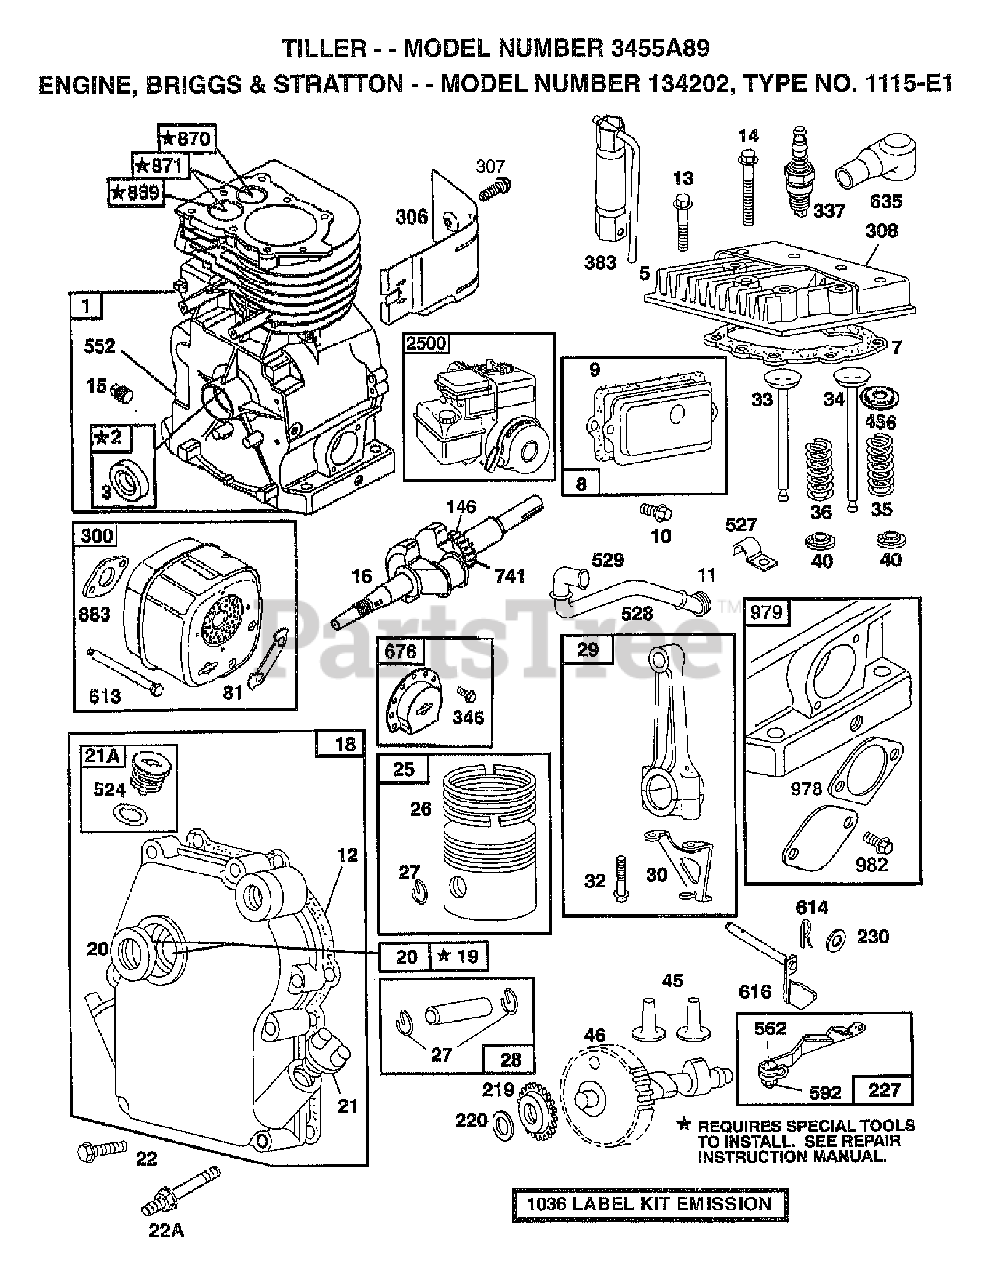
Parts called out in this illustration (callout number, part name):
1	Poulan TBD
2	Poulan TBD
5	Poulan TBD
8	Poulan TBD
12	Poulan TBD
14	Poulan TBD
15	Poulan TBD
16	Poulan TBD
18	Poulan TBD
19	Poulan TBD
21	Poulan TBD
21A	Poulan TBD
22A	Poulan TBD
23	Poulan TBD
25	Poulan TBD
26	Poulan TBD
29	Poulan TBD
30	Poulan TBD
46	Poulan TBD
51	Poulan TBD
55	Poulan TBD
56	Poulan TBD
58	Poulan TBD
65	Poulan TBD
73	Poulan TBD
90	Poulan TBD
97	Poulan TBD
109	Poulan TBD
121	Poulan TBD
180	Poulan TBD
181	Poulan TBD
187	Poulan TBD
190	Poulan TBD
190A	Poulan TBD
191	Poulan TBD
219	Poulan TBD
300	Poulan TBD
304	Poulan TBD
306	Poulan TBD
307	Poulan TBD
308	Poulan TBD
358	Poulan TBD
373	Poulan TBD
393	Poulan TBD
394	Poulan TBD
434	Poulan TBD
455	Poulan TBD
456	Poulan TBD
526	Poulan TBD
528	Poulan TBD
535	Poulan TBD
536	Poulan TBD
542	Poulan TBD
608	Poulan TBD
616	Poulan TBD
741	Poulan TBD
779	Poulan TBD
870	Poulan TBD
883	Poulan TBD
966	Poulan TBD
967	Poulan TBD
968	Poulan TBD
971	Poulan TBD
978	Poulan TBD
979	Poulan TBD
982	Poulan TBD
995	Poulan TBD
1036	Poulan TBD
1095	Poulan TBD
2500	Poulan TBD
